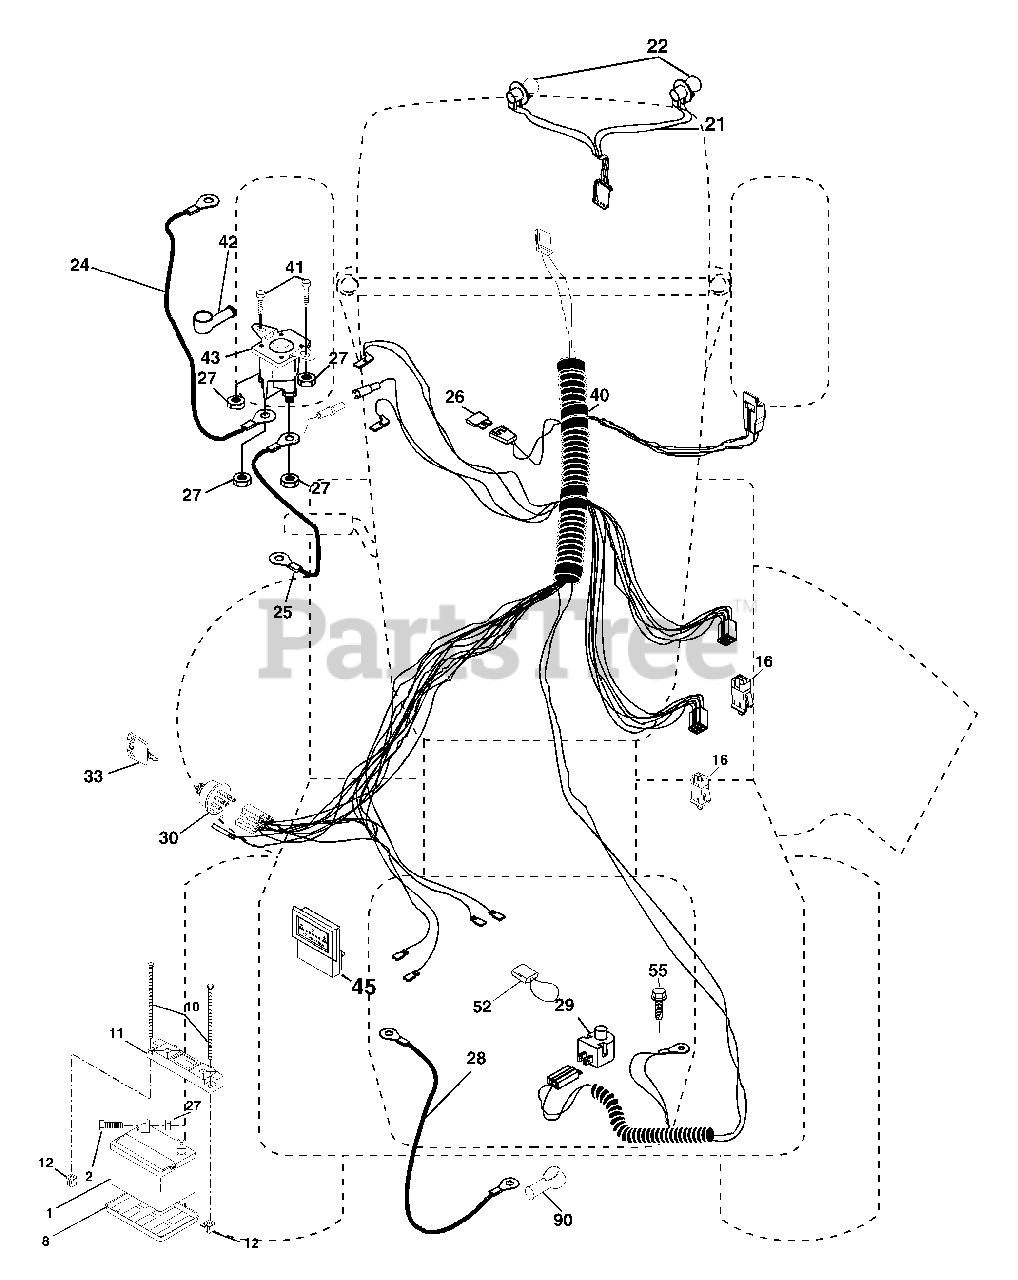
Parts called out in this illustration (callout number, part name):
1	Battery
2	Bolt Hex Hd 1/4-20 unc x 3/4
8	Tray Battery
10	Bolt 1/4-20 x 7.5
11	Hold down Battery Front Mount
12	Nut Push Nylon 1/4
16	Switch Interlock
21	Harness Asm Light W/4152j
22	Bulb Light #1156
24	Cable Battery 6 Ga. 11" red
25	Cable Battery 6 Ga. 22" red w/16 wire
27	Nut Keps Hex 1/4-20 unc
28	Cable Ground 6 Ga. 21" black
29	Switch Plunger Gray
30	Switch Ign Delta
33	Key Ign Molded Generic
40	Harness Ign.
41	Bolt Blk Fin Hex 1/4 - 20 x 1/2
42	Cover Terminal Red
43	Solenoid
45	Ammeter Rectangular 15 amp
52	Protection Wire Loop
55	Screw THDROL 5/16-18 x 1/2
